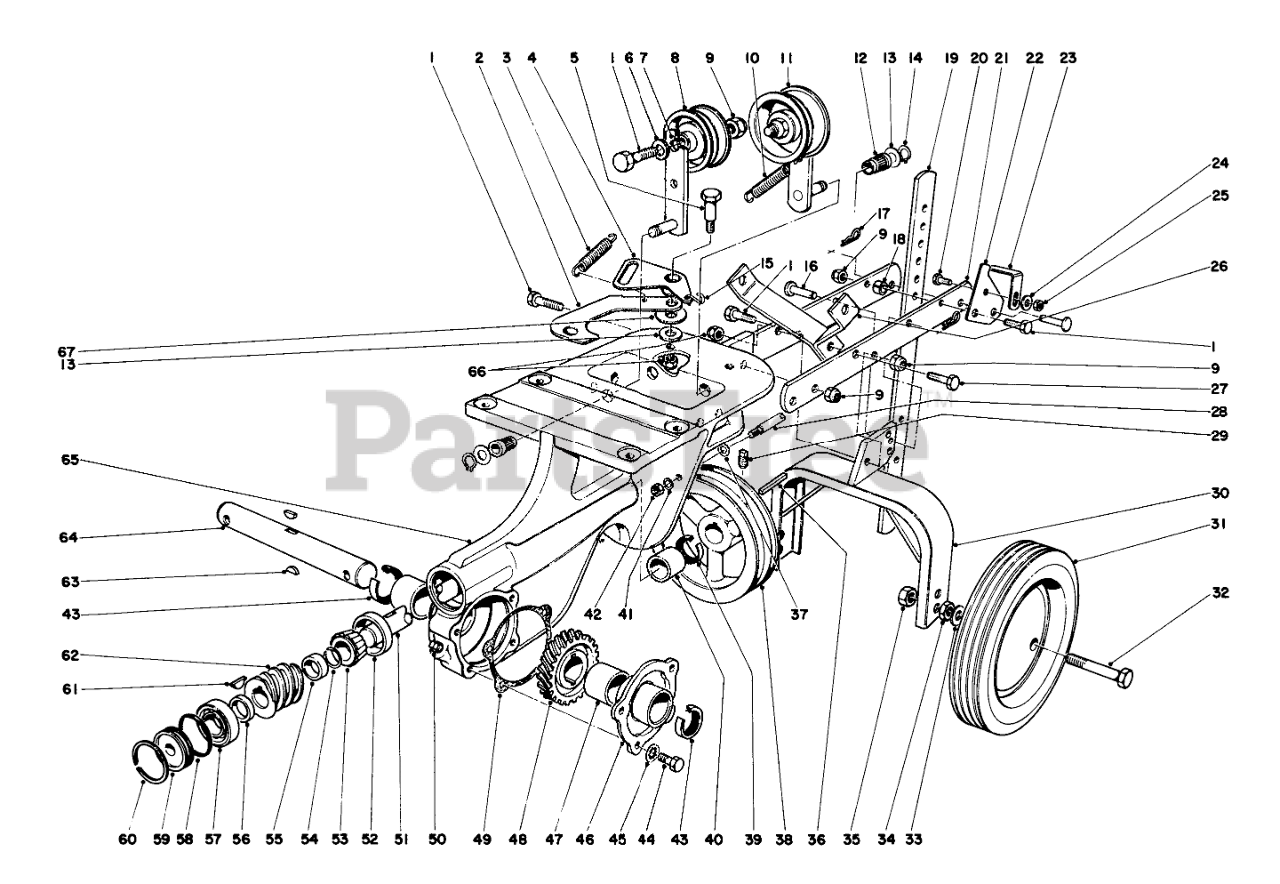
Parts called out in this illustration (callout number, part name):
1	SCREW-HH
2	Rev. Link
3	Spring
4	Bellcrank
5	SCREW-SHOULDER, HH
6	WASHER-FLAT
7	Idler
8	PULLEY IDLER
9	NUT-LOCK, CONE
10	Spring
11	PULLEY-IDLER
12	IDLER BRG
13	WASHER-PLAIN
14	RING-RETAINING, EXT
15	S Hook
16	TINE PIN
17	PIN-COTTER, HAIR
18	Spacer
19	DEPTH GAGE
20	SCREW-HH
21	Drawbar
22	Hinge Latch
23	Drag Bar Latch
24	WASHER-FLAT
25	NUT-LOCK, CONE
26	Handle Support
27	SCREW-HH
28	Belt Guide
29	SCREW-SET, HSH
30	Wheel Bracket
31	Wheel
32	Axle
33	WASHER-FLAT
34	NUT-JAM
35	1/2-13 CONELOCK NUT
36	KEY-SQUARE
37	WASHER-FLAT
38	Pulley
39	SEAL-OIL
40	BUSHING
41	WASHER-LOCK/EXT
42	NUT-JAM
43	SEAL-OIL
44	SCREW-HH
45	WASHER-LOCK
46	Cover
47	Bearing
48	WORM WHEEL
49	GASKET
50	PLUG-PIPE, SQH
51	WORM SHAFT
52	1.750 ROLLER BRG CUP
53	3/4 ROLLER BRG CONE
54	RETAINER RING
55	WORM SHF REAR SPACER
56	SPACER
57	.750 BALL BEARING
58	O-RING
60	INTRNL RETAINING RING
61	KEY-WOODRUFF
62	WORM GEAR
63	KEY-WOODRUFF
64	WORM WHEEL SHAFT
65	Chassis
66	NUT-LOCK, CONE
67	WASHER-FLAT
